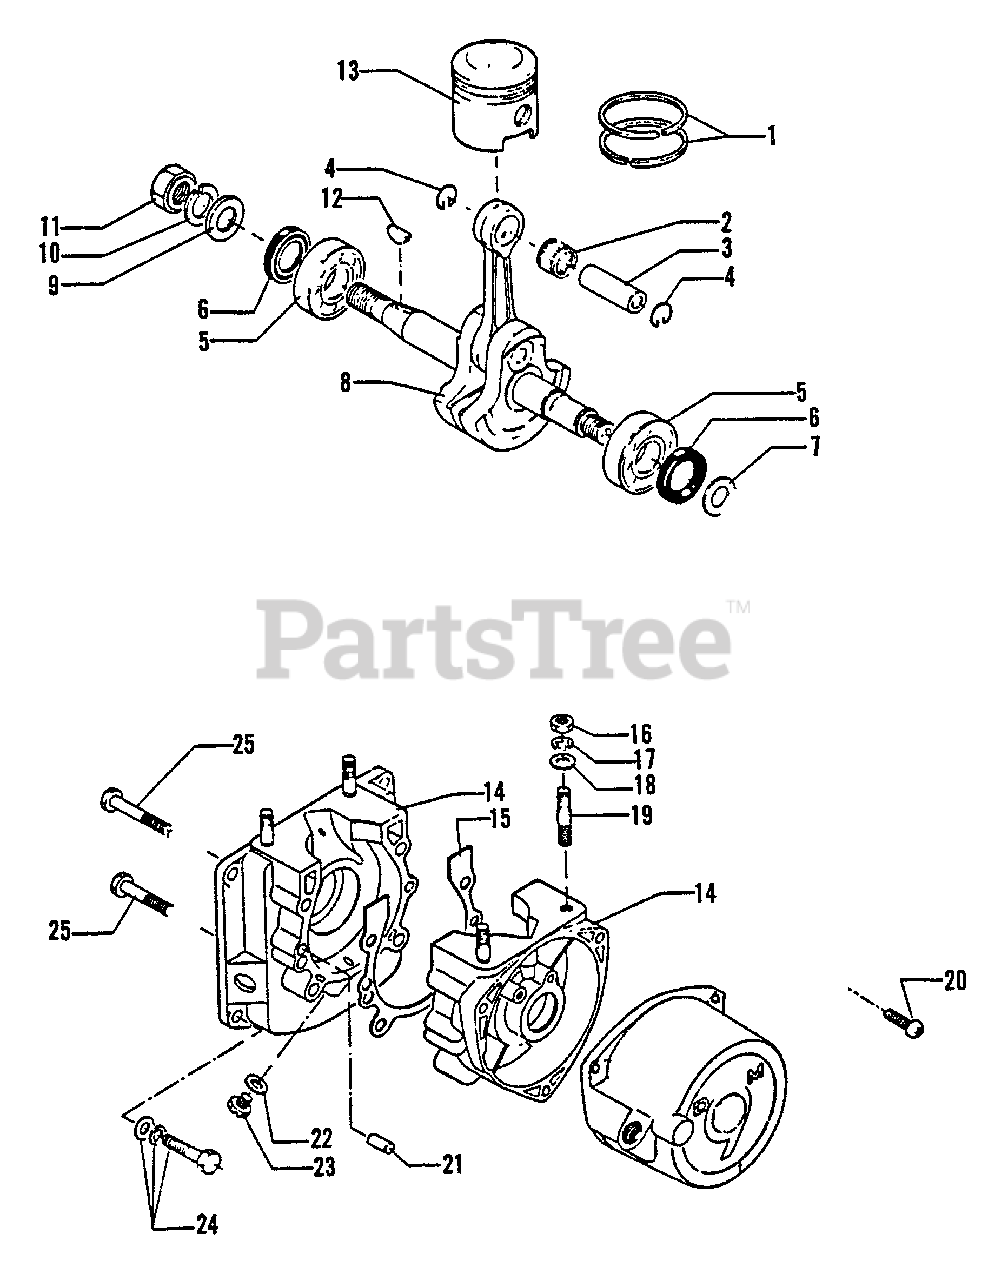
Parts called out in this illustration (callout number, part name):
1	RING, PISTON
2	BEARING, NEEDLE
3	PIN, PISTON
4	RING, RETAINING - 8
5	BEARING, BALL - 6202
6	SEAL, OIL
7	WASHER, CLUTCH
8	CRANKSHAFT ASSY
10	LOCKWASHER
13	PISTON
14	CRANKCASE KIT
15	GASKET, CRANKCASE
16	LOCKNUT - 6
17	LOCKWASHER - 6
18	WASHER - 6
20	SCREW - 5X16
21	PIN - LOCATING
23	BOLT, DRAIN
24	BOLT - 6X25
